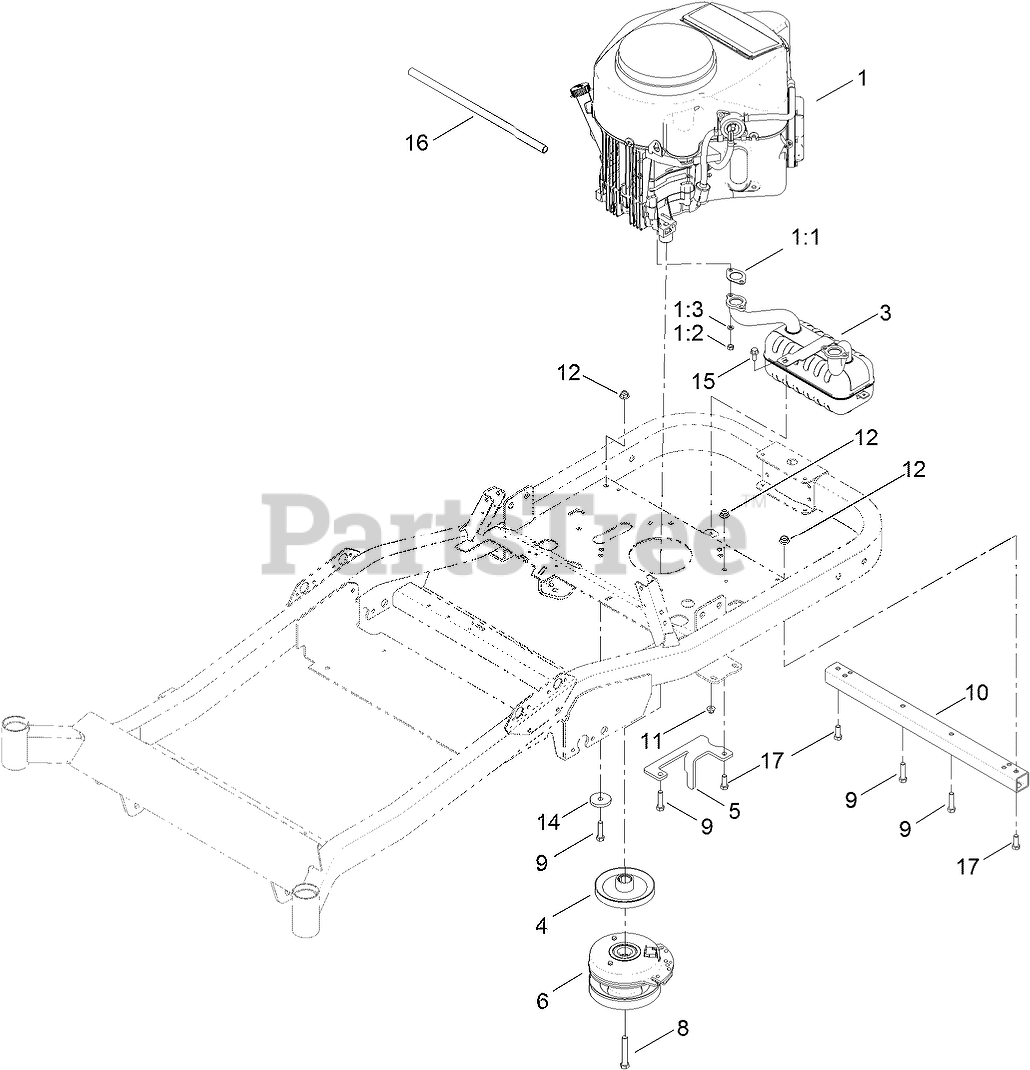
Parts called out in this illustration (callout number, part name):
1:1	GASKET-EXHAUST
1:3	WASHER-LOCK
3	MUFFLER-KAWASAKI TWIN
4	PULLEY-ENGINE
5	BRACKET-STOP, PTO
6	CLUTCH-PTO
8	SCREW-HH
9	BOLT-HH
10	TUBE-STIFFENER
11	NUT-HF, NI
12	NUT-HF, NI
14	WASHER-PLAIN
15	SCREW-HHF
16	TUBE-DRAIN, OIL
17	SCREW-HH
